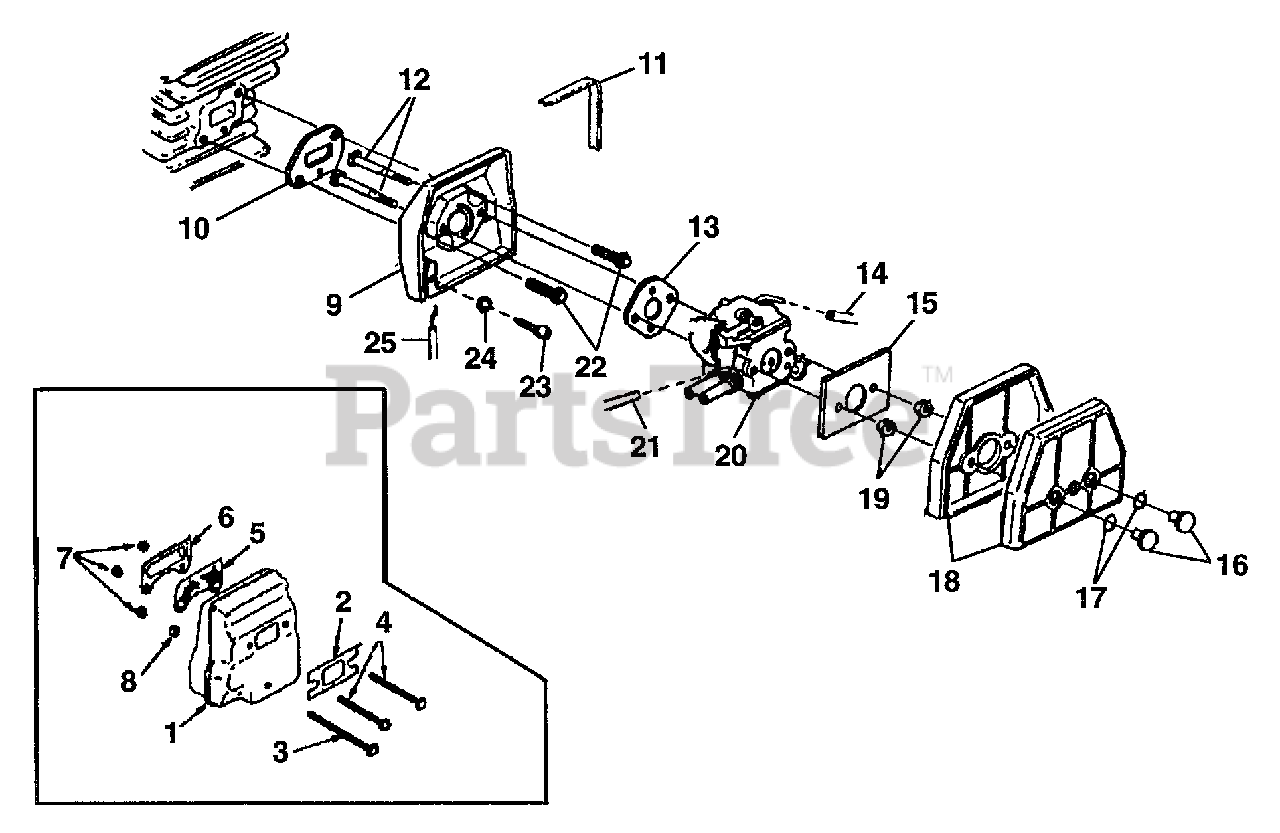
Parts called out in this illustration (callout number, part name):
1	MUFFLER - Complete
2	GASKET-Muffler
3	SCREW- Square Hd. (10-32 x 2 1/2)
4	SCREW- Square Hd. (10-32 x 2 1/4)
5	SCREEN-Spark Arrestor
6	COVER- Exhaust
7	NUT Locking Hex (10-32)
8	WASHER- Flat (#12)
9	SPACER-Carburetor
10	GASKET- Carburetor Spacer
11	FOAM- Adhesive
12	SCREW- Carburetor Retainer
13	GASKET-Carburetor
14	TUBING-Rubber (9")
15	RETAINER PLATE
16	RETAINER NUT- Filter
17	"O" RING
18	AIR FILTER
19	NUT- Hex (#8-32)
20	CARBURETOR (Walbro WT-452)
21	TUBING- Rubber (4 3/4")
22	SCREW Mach. Hex Hd. (8-32 x 7/8")
23	SCREW Thread Form (6-19 x 5/8")
24	WASHER Flat (#6)
25	CABLE Throttle
